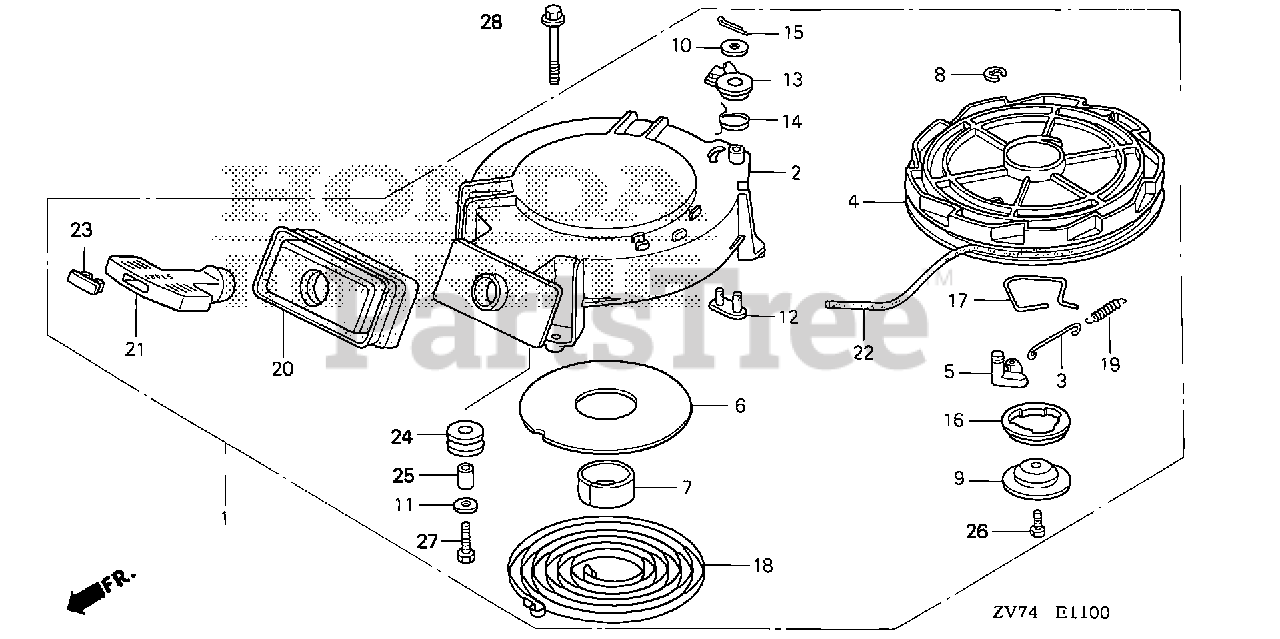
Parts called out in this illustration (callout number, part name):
1	STARTER ASSY., RECOIL
2	CASE, RECOIL STARTER
3	GUIDE, RECOIL STARTER
4	PULLEY, RECOIL STARTER
5	RATCHET, STARTER
9	PLATE, FRICTION
11	WASHER, THRUST
12	STOPPER, REEL
13	ARM, STOPPER
14	SPRING, STOPPER
15	PIN, SPLIT
17	SPRING, FRICTION
18	SPRING, RECOIL STARTER
19	SPRING, RETURN
20	SEAL, RECOIL
21	GRIP, STARTER
22	ROPE, RECOIL STARTER (NA USE ALT:08560-ZG921-11)
23	CAP, STARTER KNOB
24	ROLLER, STARTER
25	GUIDE, ROLLER
26	BOLT (6X20)
27	BOLT, HEX. (6X14)
28	BOLT, FLANGE (6X22)
